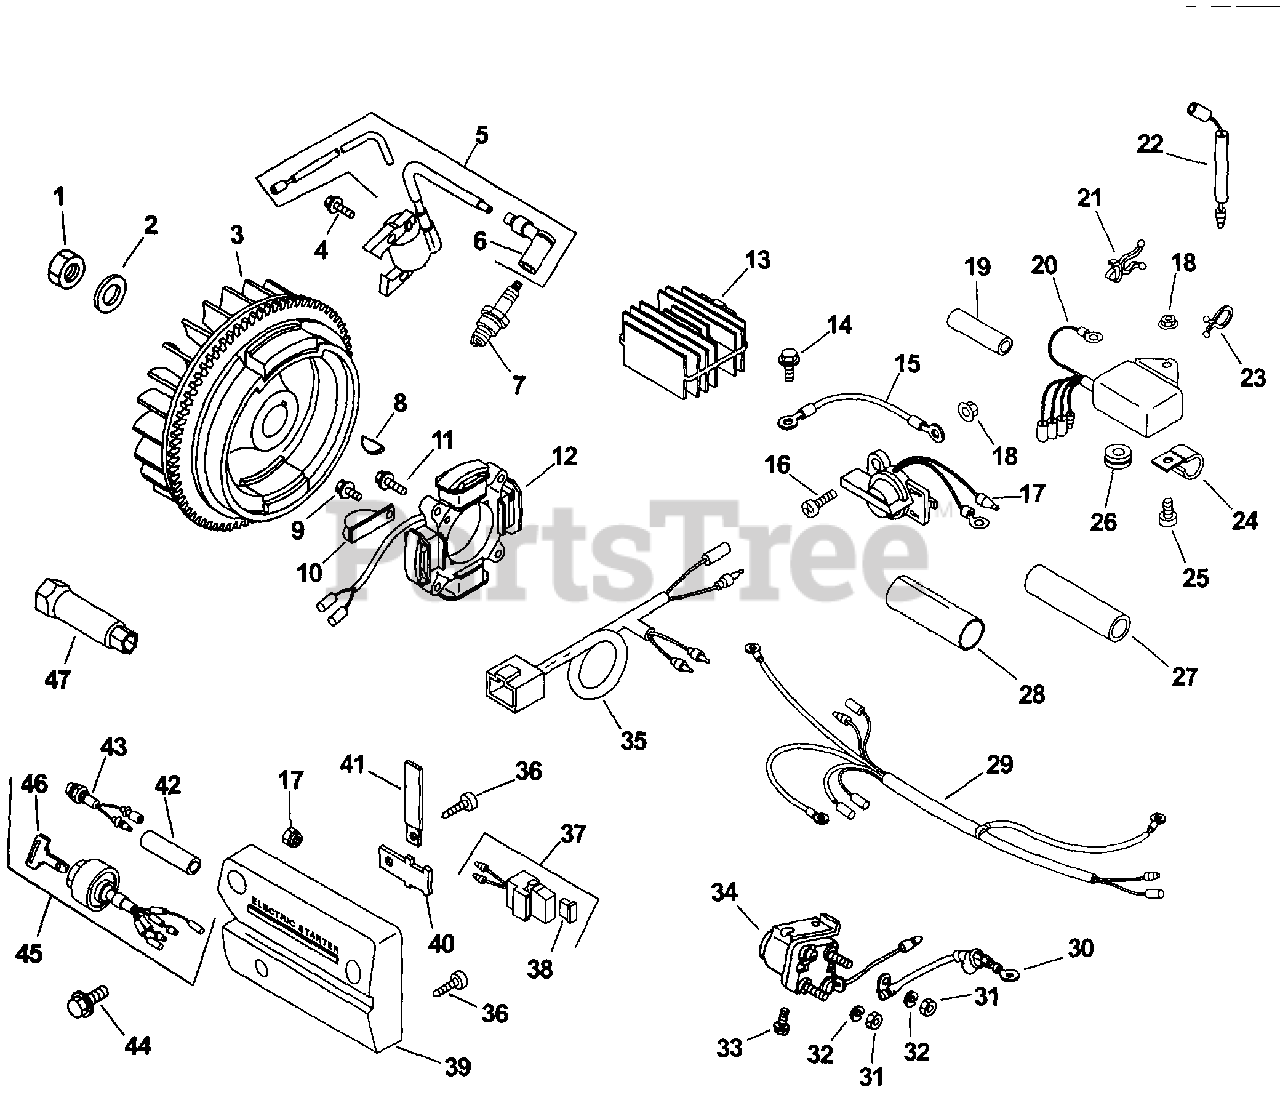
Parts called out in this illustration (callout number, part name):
3	FLYWHEEL, MANUAL START - DISCONTINUED
5	KIT, IGNITION MODULE
6	CAP ASSEMBLY
7	SPARK PLUG
8	KEY, WOODRUFF
16	SCREW, STOP SWITCH
17	STOP SWITCH
18	NUT, STOP SWITCH
19	SLEEVE, WIRING
20	OIL SWITCH ASSEMBLY
21	CLAMP, WIRE
25	SCREW, PAN HEAD
43	OIL LIGHT
